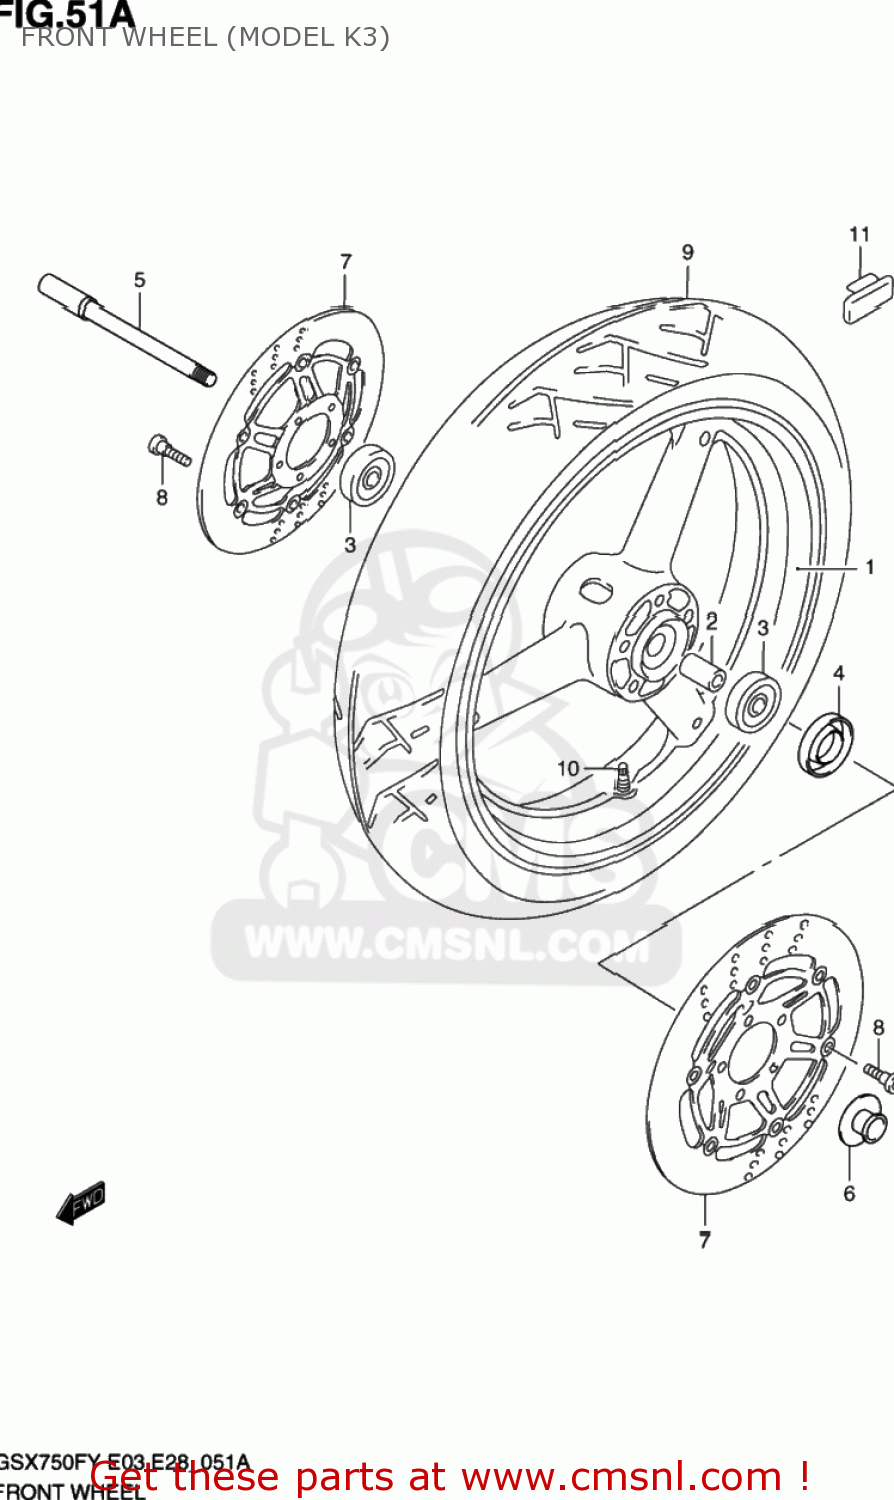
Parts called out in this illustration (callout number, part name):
1	WHEEL,FR(17M/CXMT3.50)
2	SPACER(17.5X25X88)
3	BEARING
4	SEAL,OIL(22X40X7)
5	AXLE,FR
6	SPACER,FR AXLE,L
7	DISC,FRONT BRA
8	BOLT(8X21)
9	TIRE,FR(120/70 ZR17 58W)
10	VALVE ASSY,WHEEL RIM(TR412)
11	BALANCER,WHEEL (10G)
